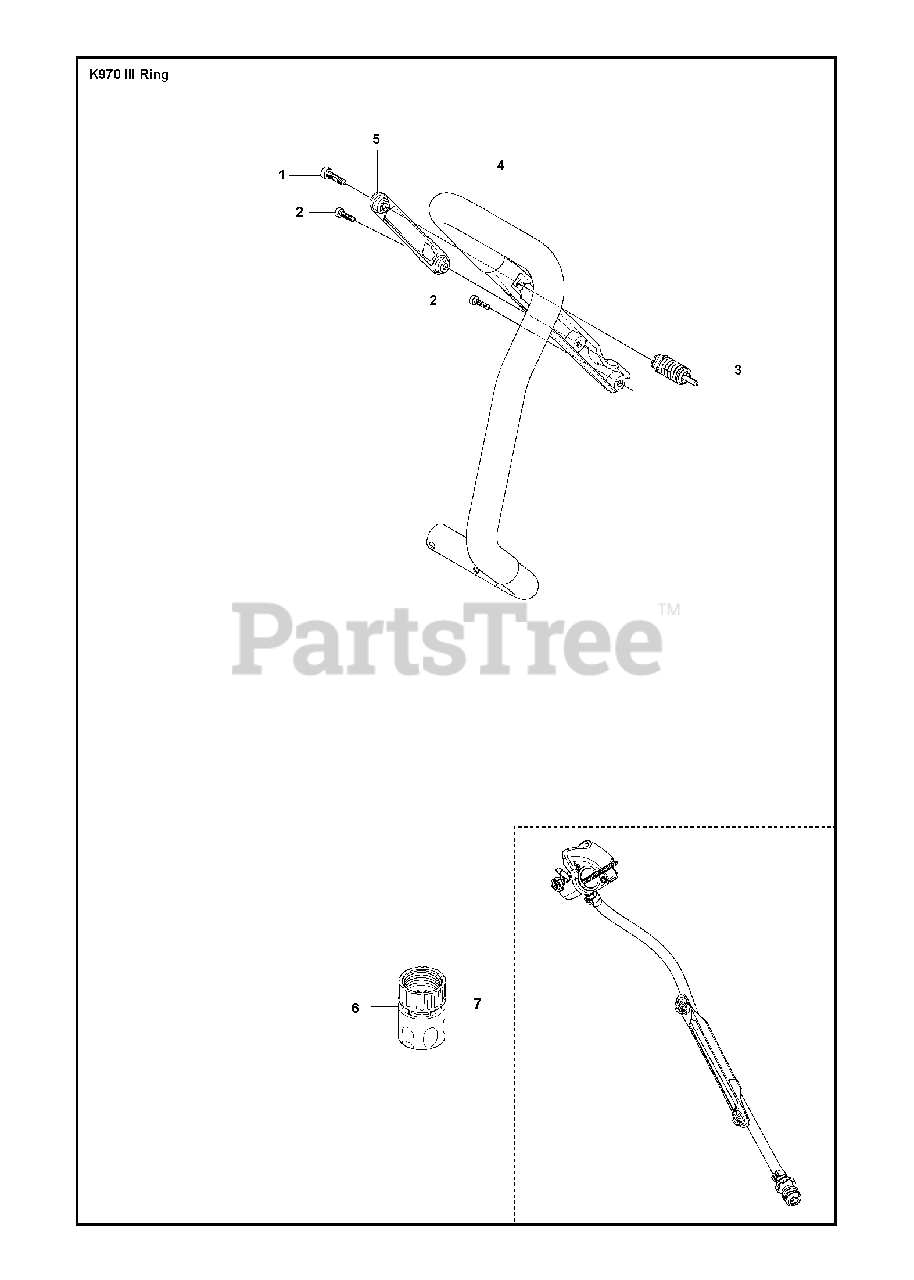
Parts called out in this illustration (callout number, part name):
1	SCREW ITXSCM
2	SCREW ITXSCT
3	ANTIVIBRATION ELEMENT
6	COUPLERGHT 3/4"
